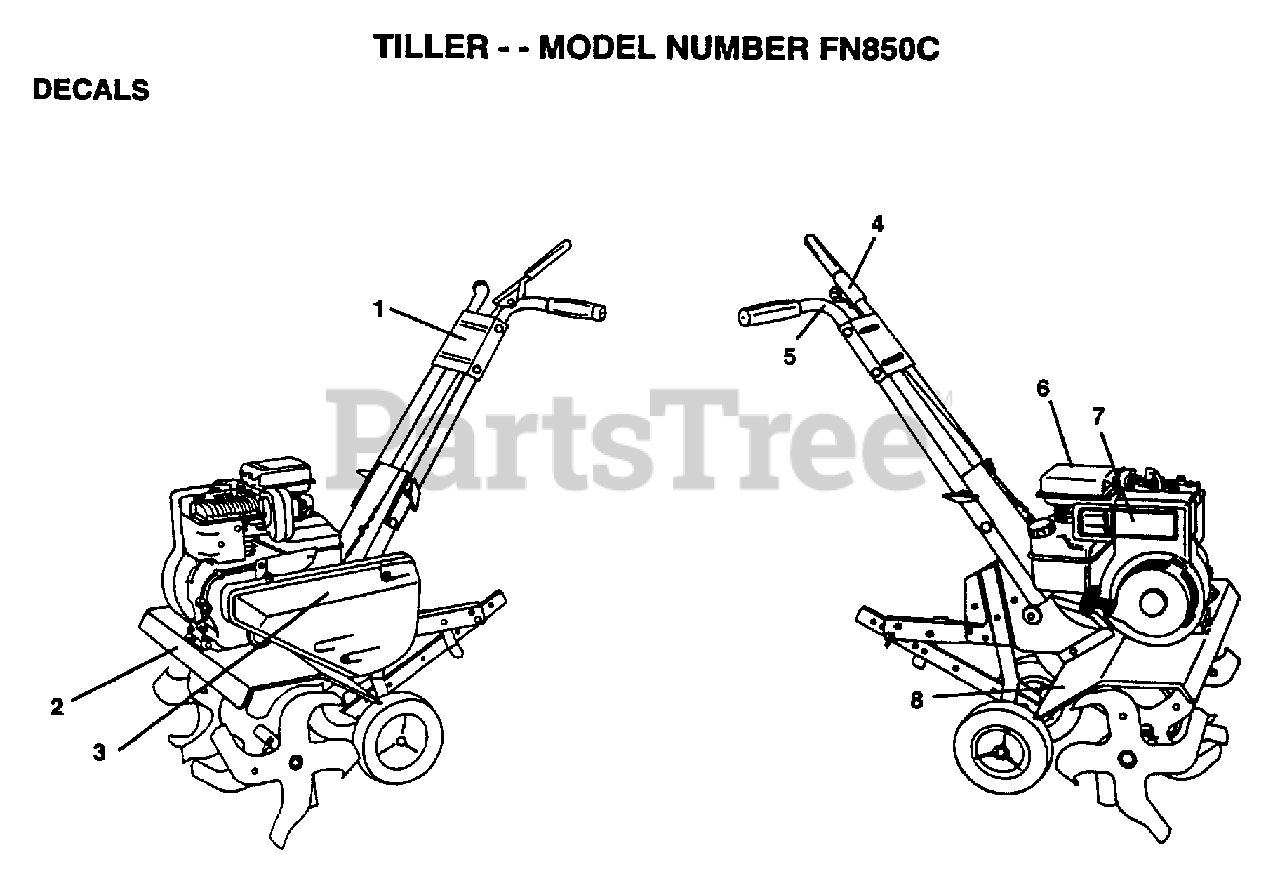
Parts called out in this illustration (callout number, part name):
1	DECAL HANDLE BRKT
2	DECAL TINE SHIELD
3	BELT.GUARD.DECAL
4	DECAL TI
5	DECAL TI
6	DECAL TI
7	DECAL, BRIGGS & STRATTON
